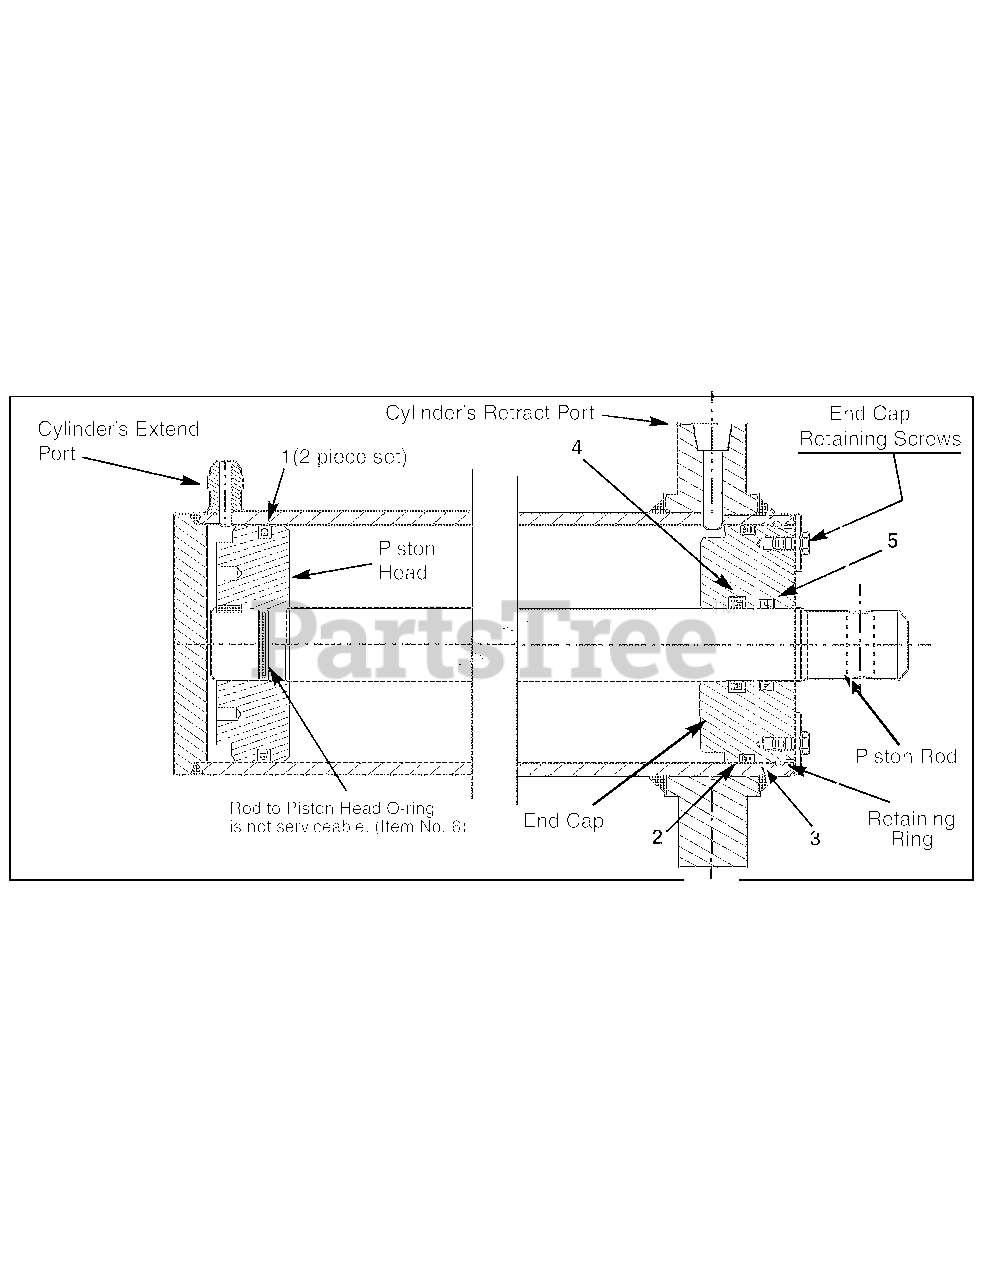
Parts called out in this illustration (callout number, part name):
1	Piston Seal: 2 piece set (White outer ring w/ black flat under ring)
2	O-ring (Large, Black)
3	Backup Ring (Black)
4	Rod-Guide U-Cup (Dark Blue)
5	Scraper: Rod (Black)
6	O-ring (Small, Black) NOT USED
7	INSTRUCTION SHEET
